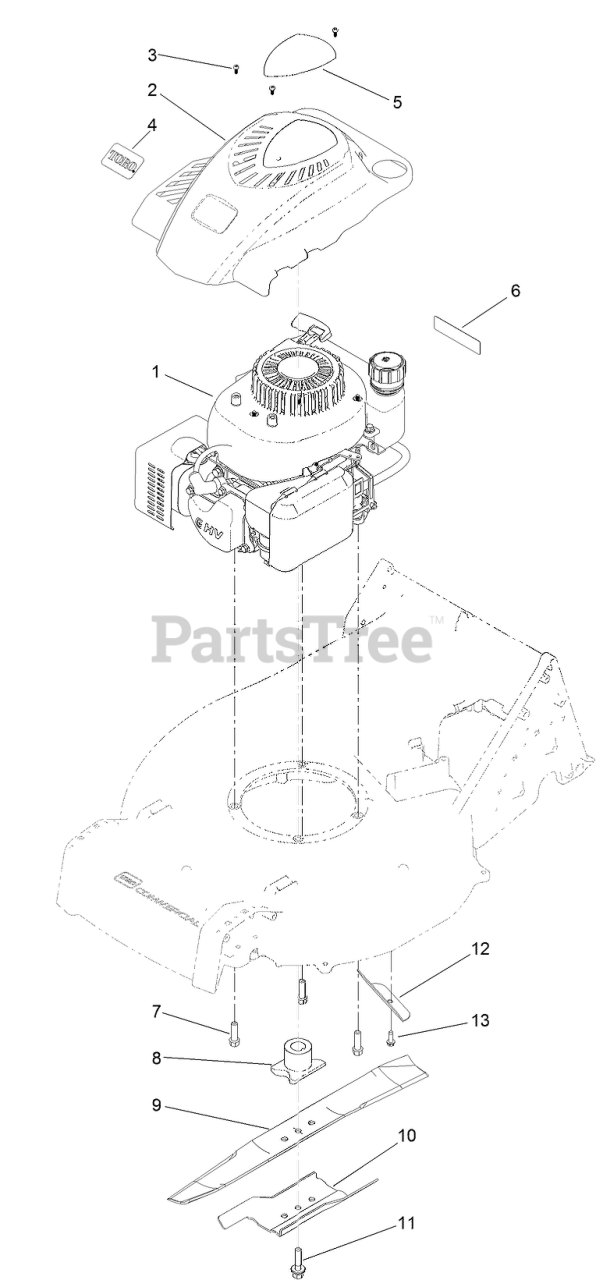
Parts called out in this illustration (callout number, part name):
1	ENGINE-1P65FC
2	SHROUD
3	SCREW-PPH
5	DECAL-ENGINE
6	DECAL-ARRESTER, SPARK
7	SCREW-TAPTITE
8	DRIVER-BLADE
9	BLADE-RECYCLING
10	ACCELERATOR-BLADE
11	BOLT-BLADE
12	SHIELD-GRASS
13	SCREW-HWHTF
